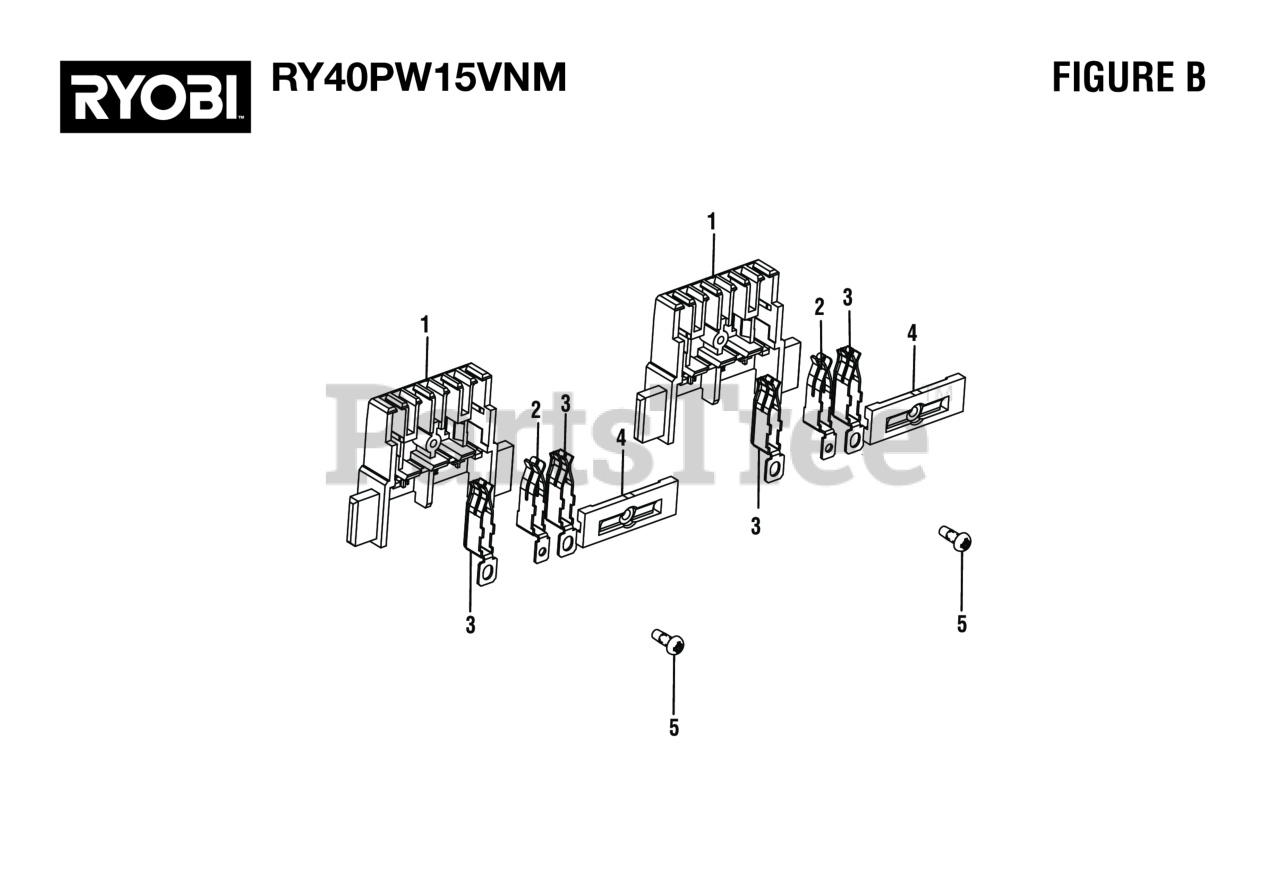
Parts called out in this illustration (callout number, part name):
1	Battery Contact Holder
2	STAMPING I BATTERY CONTACT PLATE TERMINA
3	Contact Plate Terminal
4	Battery Cover Connector
5	Screw (M3 x 8 mm, Pan Hd., Pan Hd)
